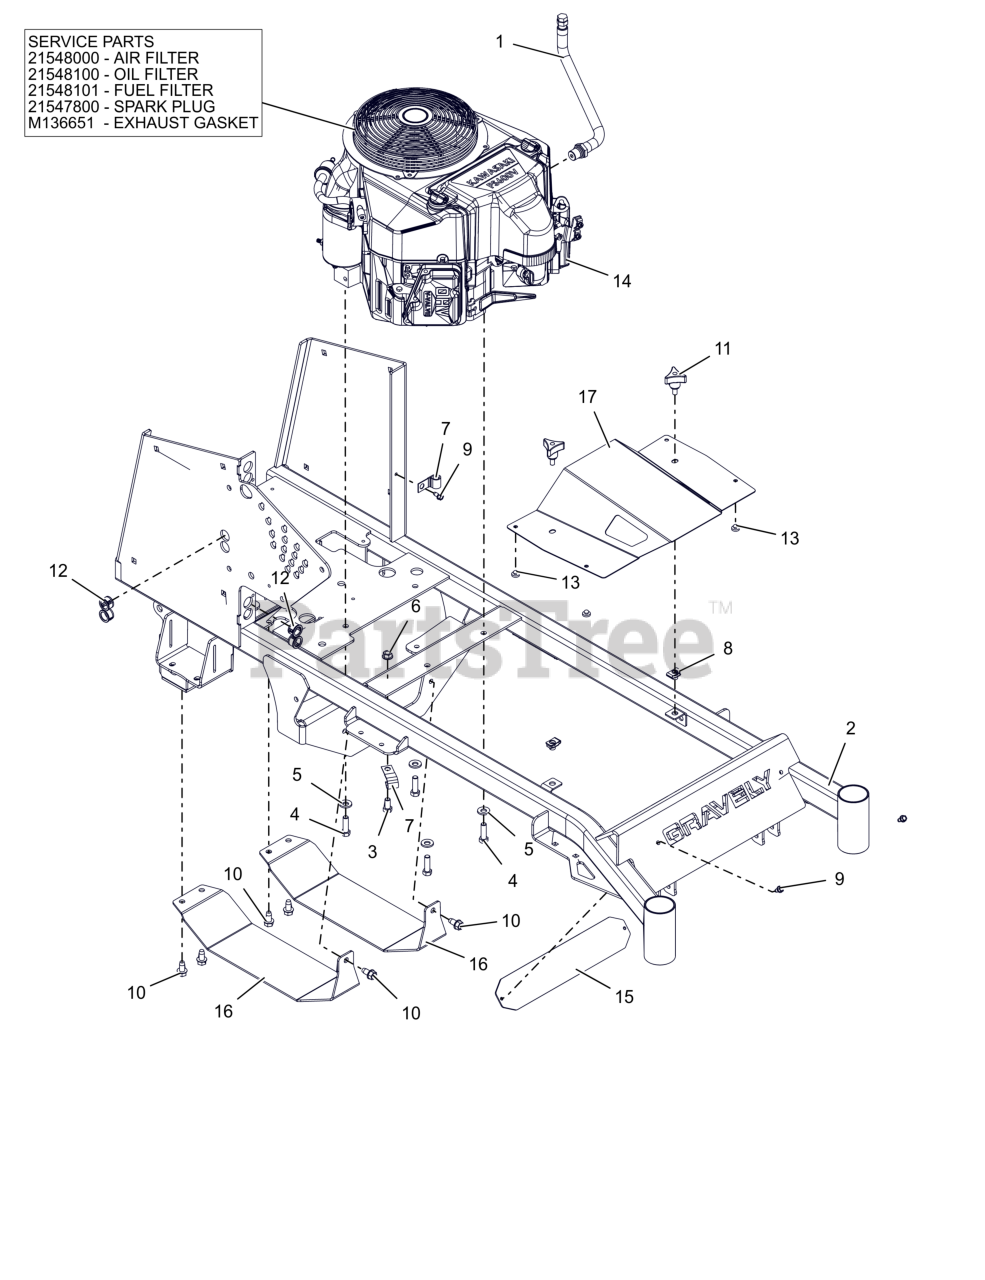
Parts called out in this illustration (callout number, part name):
1	HOSE, OIL DRAIN
2	32" MAIN FRAME WMT W/SAFETY
3	BLT,HEX .38-16X.75 G5 ZCC
4	BLT, HEX .38-16X1.25 G5 ZCC NT
5	WASHER, 3/8" SPRING DISC
6	NUT-LK-CTR-FLG .375-16 GF ZCC
8	NUT-CLIP RETAINER 5/16-18X.56
9	SCR-TAP .25-20X.50 HWH ZCC
10	SCR,TAP .375-16X.75 HWH TR ZCC
11	KNOB,WING STUD 5/16-18 X .75
12	BUSH, PANEL SNAP .687X.875X.56
13	BUMPER GROMMET
14	ENG. KAW FS600
14	AIR FILTER, KAWASAKI FR
14	OIL FILTER, KAWASAKI FR
14	FUEL FILTER-KAWASAKI FR
14	SPARK PLUG, KAWASAKI FR
14	GASKET, MUFFLER #
15	PLATE-BUMPER LOGO BACKING(BLK)
16	BRKT, 32" SKID PLATE (BLACK)
17	32" BELT COVER W/SAFETY DECALS
